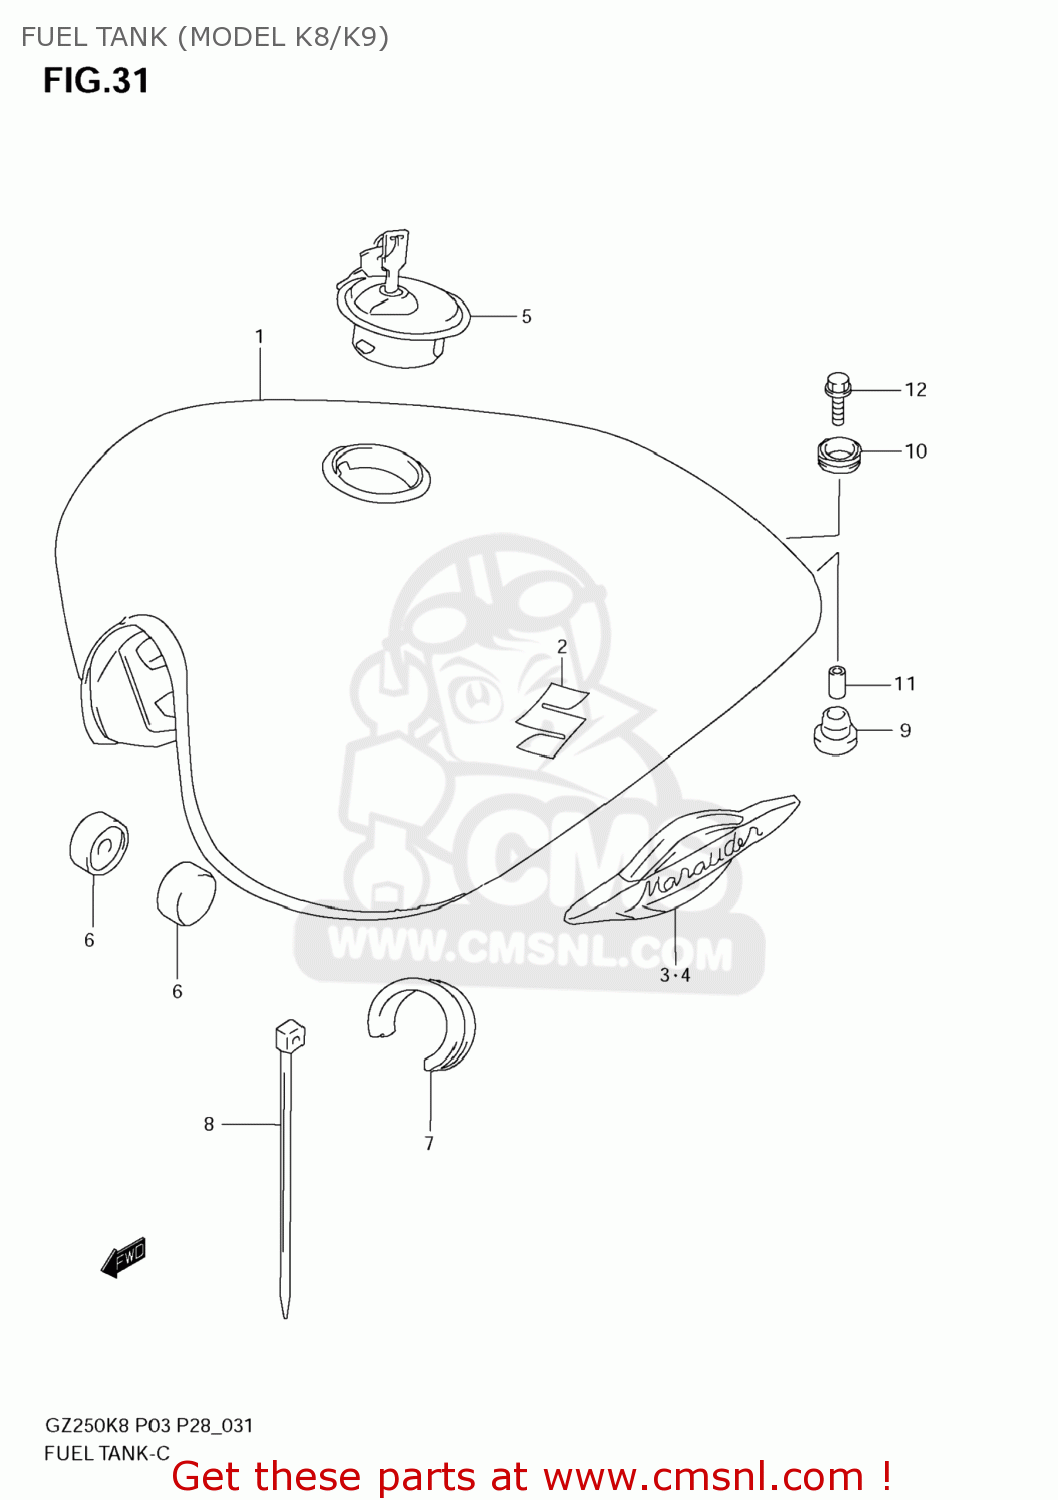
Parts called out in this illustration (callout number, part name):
1	TANK ASSY,FUEL(GRAY)
2	EMBLEM,S
5	CAP SET,FUEL TANK
6	CUSHION
7	CUSHION,FUEL TANK SIDE
8	CLAMP
9	CUSHION
10	CUSHION,FUEL TANK RR
11	SPACER(6.5X9X18)
12	BOLT
